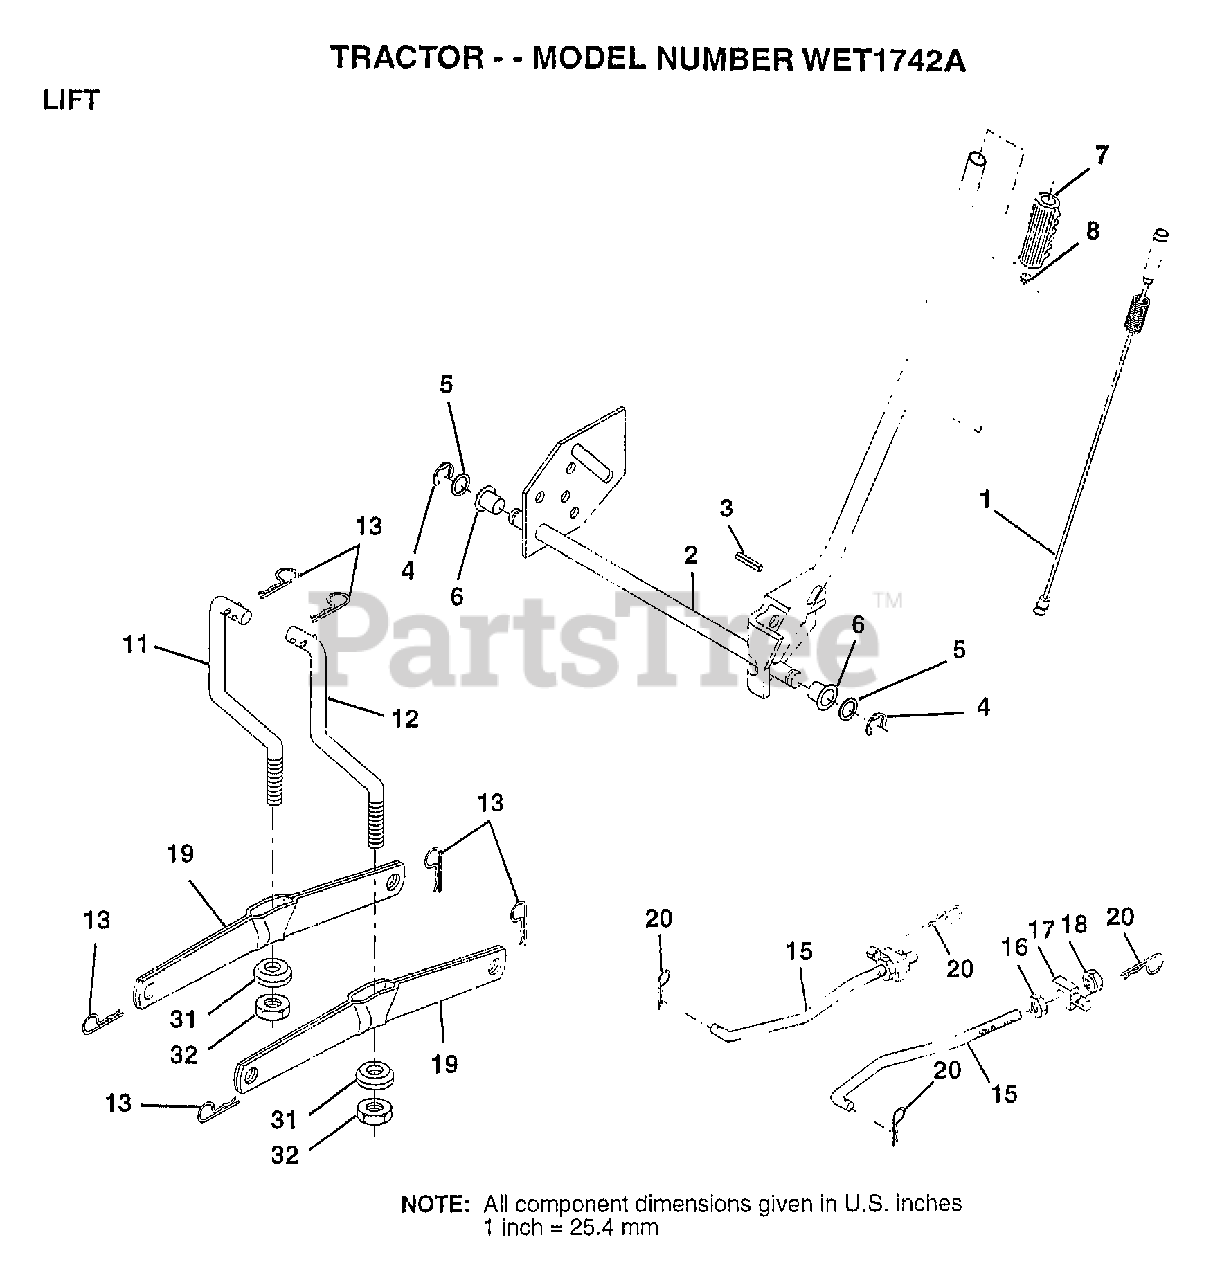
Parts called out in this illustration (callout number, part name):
1	WIRE ASM W.SPRING
2	"SHAFT ASM LIFT,RH"
3	PIN-GROOVE LT
5	WASHER
6	NYLON BEARING
7	GRIP
15	LINK.FRONT
16	NUT
17	TRUNION
18	NUT.LK.W/WSH.1/2.
19	ARM SUSP REAR
20	RETAINER.SPRING
31	BEARING PVT LH
32	NUT.CROWNLOCK.3/8
